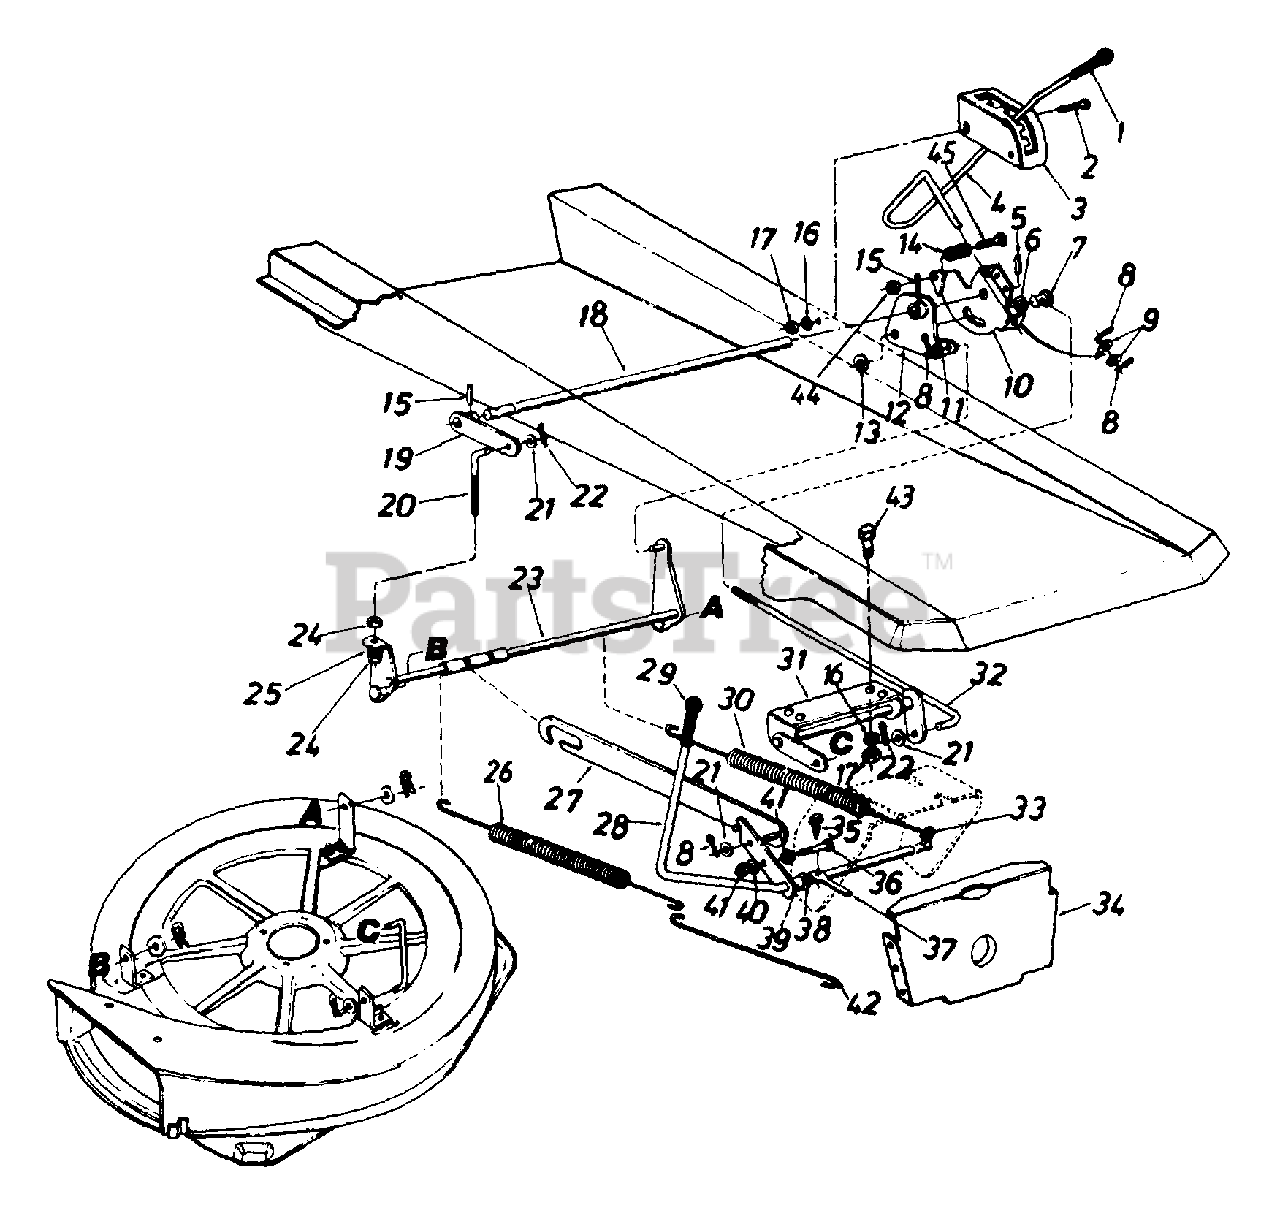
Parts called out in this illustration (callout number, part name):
2	Truss Mach. Scr. 5/16-18 x .75" Lg.
5	Spring Pin Spir. 3/16" Dia. x 1.50" Lg.
6	Fl-Wash. .385" I.D. x.87" O.D.
7	Adj. Ferrule Deck Lift Handle
8	Cotter Pin 1/8" Dia. x 1.0"
9	Fl-Wash. .531" I.D. x .930" O.D.
12	Deck Lift Brkt. Ass'y.- L.H.
13	Fl-Wash. .635" I.D. x 1.04" O.D.
14	Compression Spring .5" Dia. x .5" Lg.
15	Spring Pin Spir. 1/4" Dia. x 1.50" Lg.
16	L-Wash. 5/16" I.D.
17	Hex Nut 5/16-18 Thd.
18	Rear Hgt. Adj. Shaft
19	Deck Lift Brkt. Ass'y.- R.H.
20	Deck Adj. Scr. 3/8-16 Thd.
21	Fl-Wash. .385" I.D. x .87" O.D.
22	Intern. Cotter Pin 1/2" Dia.
23	Deck Link Ass'y. -Rear
24	Hex Nut 3/8-16 Thd.
25	L-Wash. 3/8" I.D.
26	Extension Spring 13.25" Lg.
30	Extension Spring 13.25" Lg.
31	Deck Lift Ass'y.- Front
32	Deck Lift Connecting Rod
33	Clevis Pin Special .250" Dia.
36	Hex Bolt 5/16-18 x 1.50" Lg. (Grade 5)
37	Switch Actuator
38	Fl-Wash. .531" I.D. x .930" O.D.
39	Spacer .511" I.O. x .70" O.D. x .38" Lg.
40	L-Wash. 5/16" I.D.
41	Hex Nut 5/16-18 Thd.
42	Spring Hook
43	Hex Bolt 5/16-18 x .75" Lg.
44	Hex Cent. L-Nut 1/4-20 Thd.
45	Hex Bolt 1/4-20 x 1.25" Lg.
